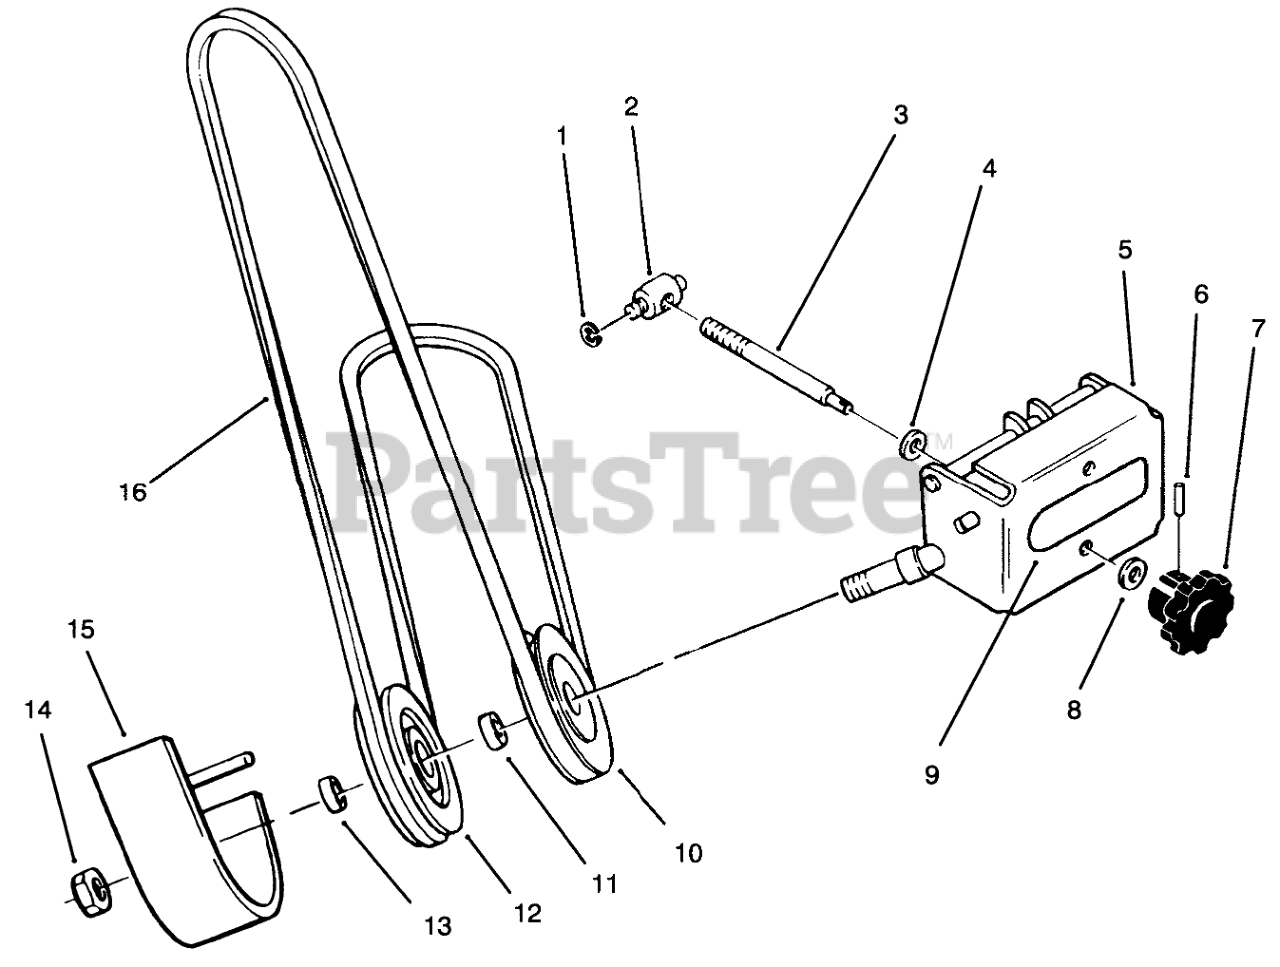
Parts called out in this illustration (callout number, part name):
1	RING-RETAINING
2	TRUNNION-DOUBLE
3	ROD ADJ
4	WASHER-FLAT
5	Front Support
6	PIN-ROLL
7	KNOB-ADJUSTMENT
8	WASHER-SPRING
9	DECAL-ATTACH A-MATIC
10	Pulley-V
11	SPACER
12	PULLEY-FLAT IDLER
13	SPACER-OUTER
14	Nut
15	Belt Cover
16	V-BELT
